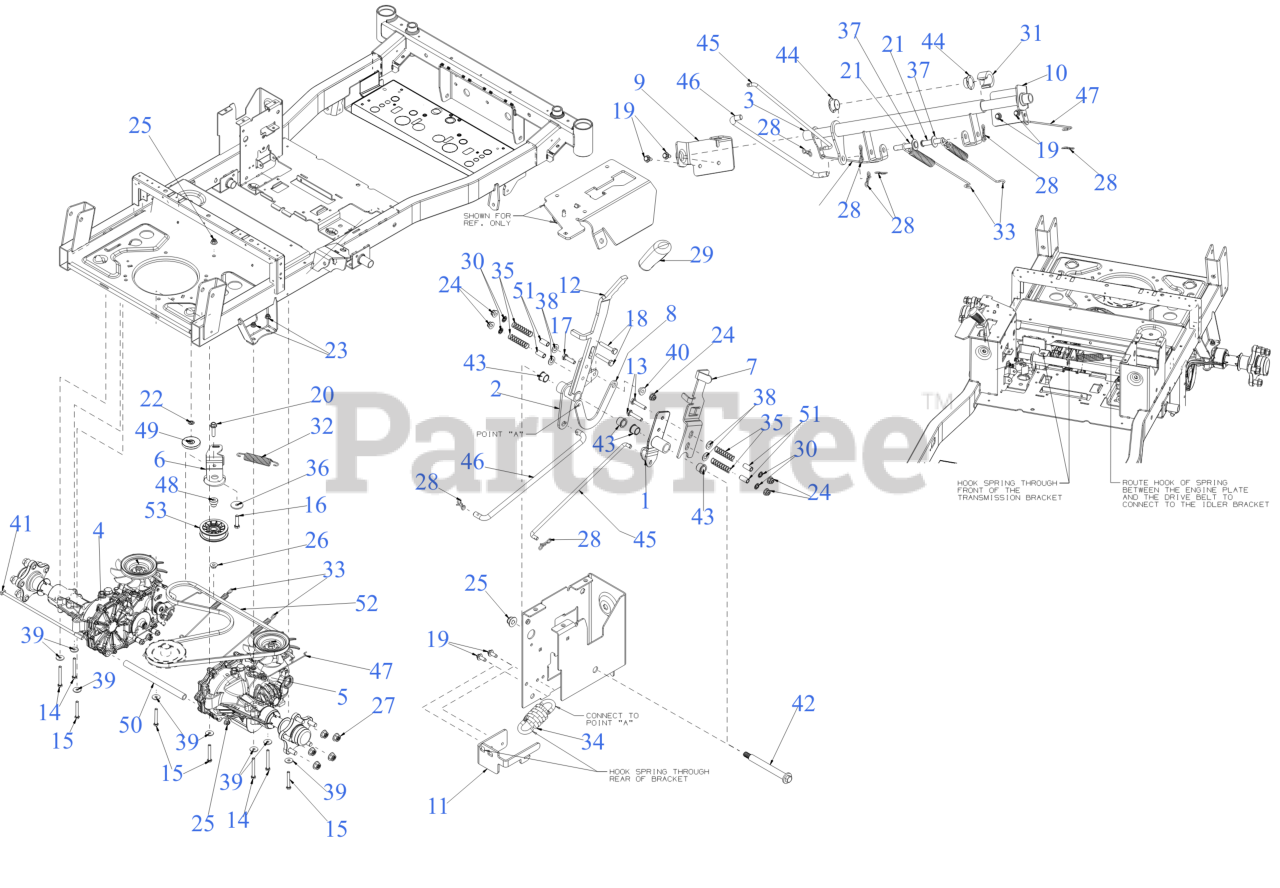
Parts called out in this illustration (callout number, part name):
1	BYPASS LEVER PIVOT ARM
2	PARK BRAKE PIVOT ARM
3	BRAKE PIVOT SHAFT
4	HYDRO TRANSMISSION (LH)
5	HYDRO TRANSMISSION (RH)
6	HYDRO DRIVE IDLER BRACKET
7	TRANSMISSION BYPASS LEVER
8	OVER CENTER LINK
9	BRAKE SHAFT SUPPORT (RH)
10	BRAKE SHAFT SUPPORT (LH)
11	SPRING MOUNTING BRACKET
12	PARK BRAKE LEVER
13	HEX SCREW 1/4-20 x 1.25
14	HEX SCREW 5/16-18 x 2.75
15	HEX SCREW 5/16-18 x 2.25 GR5
16	SCREW 3/8-16 x 1.50
17	SCREW 1/4-20 X1.00 GR5
18	SCREW 1/4-20 x 1.50 GR.5
19	SCREW M6-1 x .625
20	HEX HEAD BOLT (3/8-16:1.50 GR8)
21	CLEVIS PIN 3/8 x 1.87
23	FLANGE LOCK NUT 5/16-18
24	FLANGE LOCK NUT
26	FLANGE LOCK NUT
27	HEX FLANGE NUT 1/2-20 GR8
28	BOW TIE COTTER PIN 1/4-5/16
30	RETAINER-BOLT .25ID x .50OD
31	SPACER: .76ID x .75
32	EXTENSION SPRING .925 x 5.37
33	EXTENSION SPRING .60 DIAx9.09
34	EXTENSION SPRING 1.09x3.25
35	COMPRESSION SPRING
36	FLAT WASHER .390x1.500x.134
37	FLAT WASHER
38	WASHER THRUST .375X.70X.030
39	FLAT WASHER 1.0 OD:.331 ID
40	SHOULDER SPACER
41	SUPPORT TUBE ROD
42	SHOULDER SCREW .491x3.937 3/8-16
43	FLANGE BUSHING
44	FLANGE BEARING .75 x 1.125 x .375
45	BYPASS LINK
46	BRAKE LINK
47	HYDRO BYPASS ROD .100 DIA
48	SHOULDER SPACER
49	SHOULDER SPACER
50	SUPPORT TUBE
51	SPACER .252x.350x.760
52	TRANSMISSION DRIVE BELT A x 67
53	FLAT IDLER PULLEY 3.00 OD
